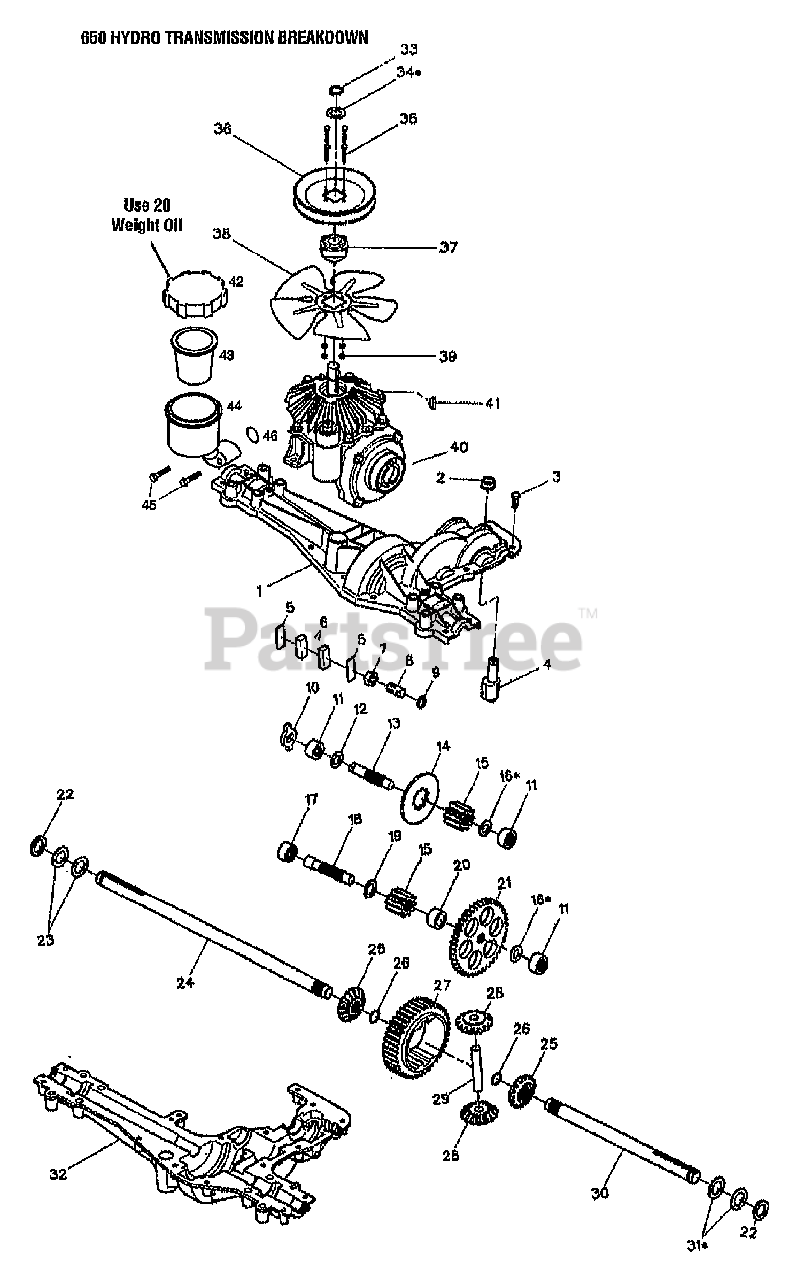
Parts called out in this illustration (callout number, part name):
1	HOUSING-UPPER
2	RING-V
3	SCR-SELF TAP 1/4-20X.734
4	ASSM-SHAFT & CAM
5	SPACER
6	BLOCK FRICTION
7	NUT-HEX/JAM
8	ADJUSTMENT-STUD
9	RING-O
10	KEY-DRIVE
11	ASSM-BEARING
12	WASHER-.505 X .942 X .040
13	SHAFT-INPUT
14	BRAKE-DISC
15	SPUR-GEAR 10T
16	KIT-SHIM (.500 SHAFT)
17	ASSM-BEARING
18	SHAFT-IDLER
19	WASHER-.632 X 1.0 X .041
20	SPACER .630 X 1.00 X .549
21	SPUR-GEAR 41T
22	WASHER-NEOPRENE
23	WASHER-.758X1.25X.031
24	AXLE-TRANSMISSION LH
25	MITER-GEAR 15T
26	RING-RETAINING
27	SPUR-GEAR 41T
28	MITER-GEAR 15T
29	SHAFT-CROSS
30	AXLE-TRANSMISSION RH
31	KIT-SHIM (.750 SHAFT)
32	HSG-TRANSMISSION LOWER
33	RING-RETAINING
34	KIT-SHIM (.670 SHAFT)
35	SCR-HHC #6-32X.88
36	PULLEY-4.50" DIA
37	HUB-PULLEY
38	KIT-FAN
39	NUT-H/LK #6-32
40	ASSM-HYDROSTATIC
41	KEY-WOODRUFF
43	DIAPHRAGM
44	RESERVOIR
45	SCR-HFLK 1/4-20X1.00
